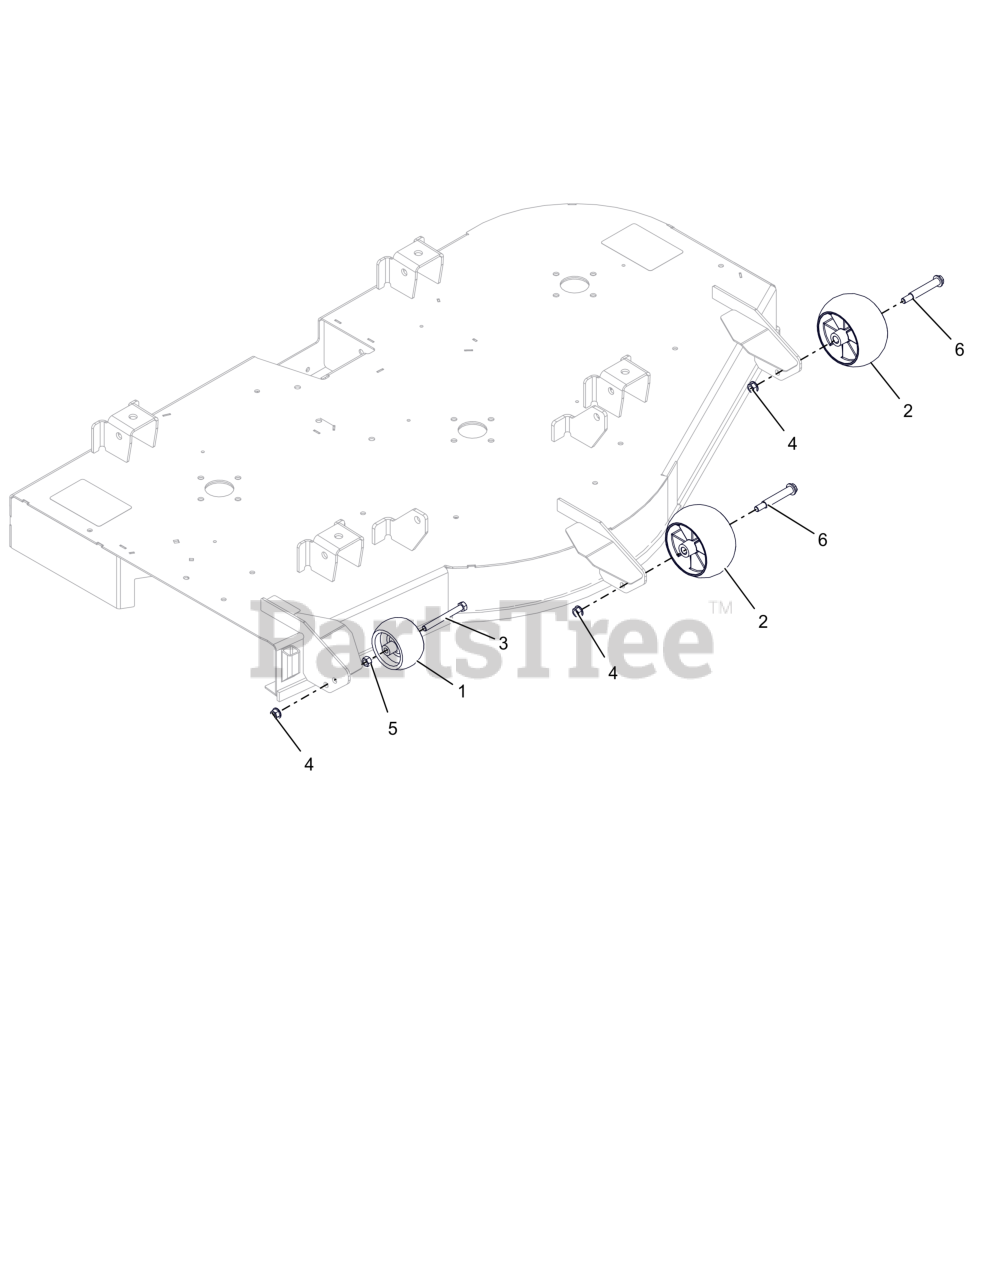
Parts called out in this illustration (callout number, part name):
2	ANTI-SCALP WHEEL - 5X OS
3	BLT, HEX .38-16X3.50 G5 ZCC
4	NUT-LK-CTR-FLG .375-16 GF ZCC
5	NUT-STD .375-16 G2 ZCC
6	BLT-SHLDR .38-16X2.50 HWH G5
